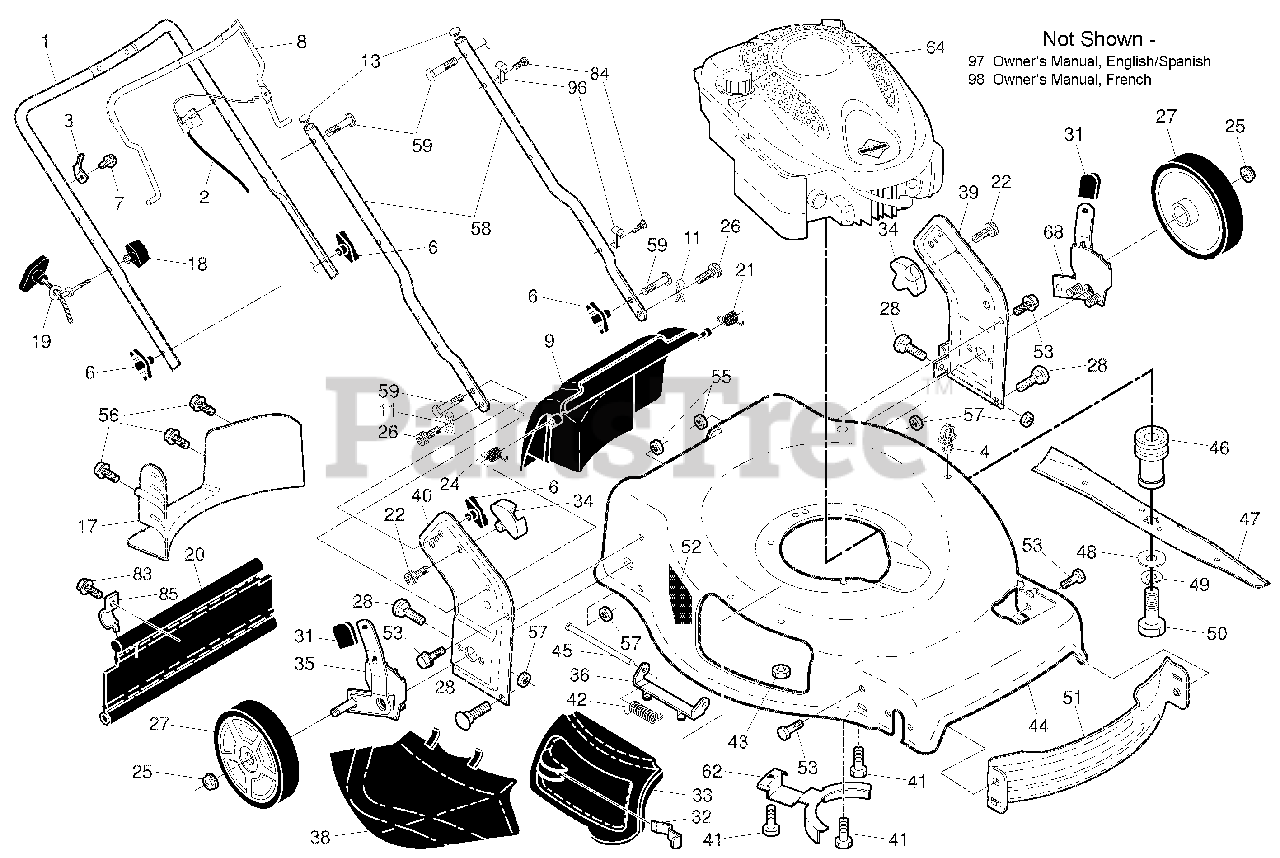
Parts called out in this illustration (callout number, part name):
1	UPPER HANDLE
2	CABLE, ENGINE ZONE CONTROL
3	UP-STOP BRACKET
4	CLIP.PUSH-IN.HINGED
6	Handle Knob
7	SCREW, HEX WASHER HEAD
8	CONTROL BAR
9	REAR DOOR ASSEMBLY
11	HAIRPIN, DOOR/HANDLE PIVOT
13	PLUG, HANDLE BAR
17	REAR BAFFLE
19	ROPE GUIDE
20	REAR SKIRT
21	SPRING, REAR DOOR, LH, BLACK
22	SCREW, PANHEAD, TORX #20
24	SPRING, REAR DOOR, RH, GREY
25	Nut, Hex
26	SCREW, REAR DOOR/HANDLE PIVOT
27	WHEEL & TIRE ASSEMBLY, REAR
28	BOLT, CARRIAGE 5/16-18 X 5/8
31	Selector Knob
32	LATCH, MULCHER DOOR
33	MULCHER DOOR
34	BRACKET, GRASSBAG
35	KIT, WHEEL ADJUSTER, REAR, RH
36	Hinge Bracket Assembly
38	DISCHARGE DEFLECTOR
39	HANDLE BRACKET, LH
40	HANDLE BRACKET, RH
41	Screw, Hex Head, Threaded, Rol
42	Spring, Torsion
43	LOCKNUT, HEX 1/4-20
44	KIT, LAWN MOWER HOUSING
45	Rod, Hinge
46	BLADE ADAPTER / PULLEY
47	BLADE, 22"
48	Hardened Washer
49	Helical Lockwasher
50	Screw, Hex Head, Grade 8 3/8-2
51	FRONT BAFFLE
52	Danger Decal
53	BOLT.5/16-18HEX.WHS.HD.LCKSERR
55	LOCKNUT, HEX 1/4-20
56	Screw, Rear Baffle
57	NUT, HEX
58	BAR, LOWER HANDLE
59	Handle Bolt
62	BELT RETAINER
68	KIT, WHEEL ADJUST, REAR, LH
84	FASTENER, PUSH
85	MOUNTING BRACKET, REAR SKIRT
96	Clip, Cable
97	OWNER'S/PARTS MANUAL (ENG/SPA)
98	OWNER'S/PARTS MANUAL (FRENCH)
